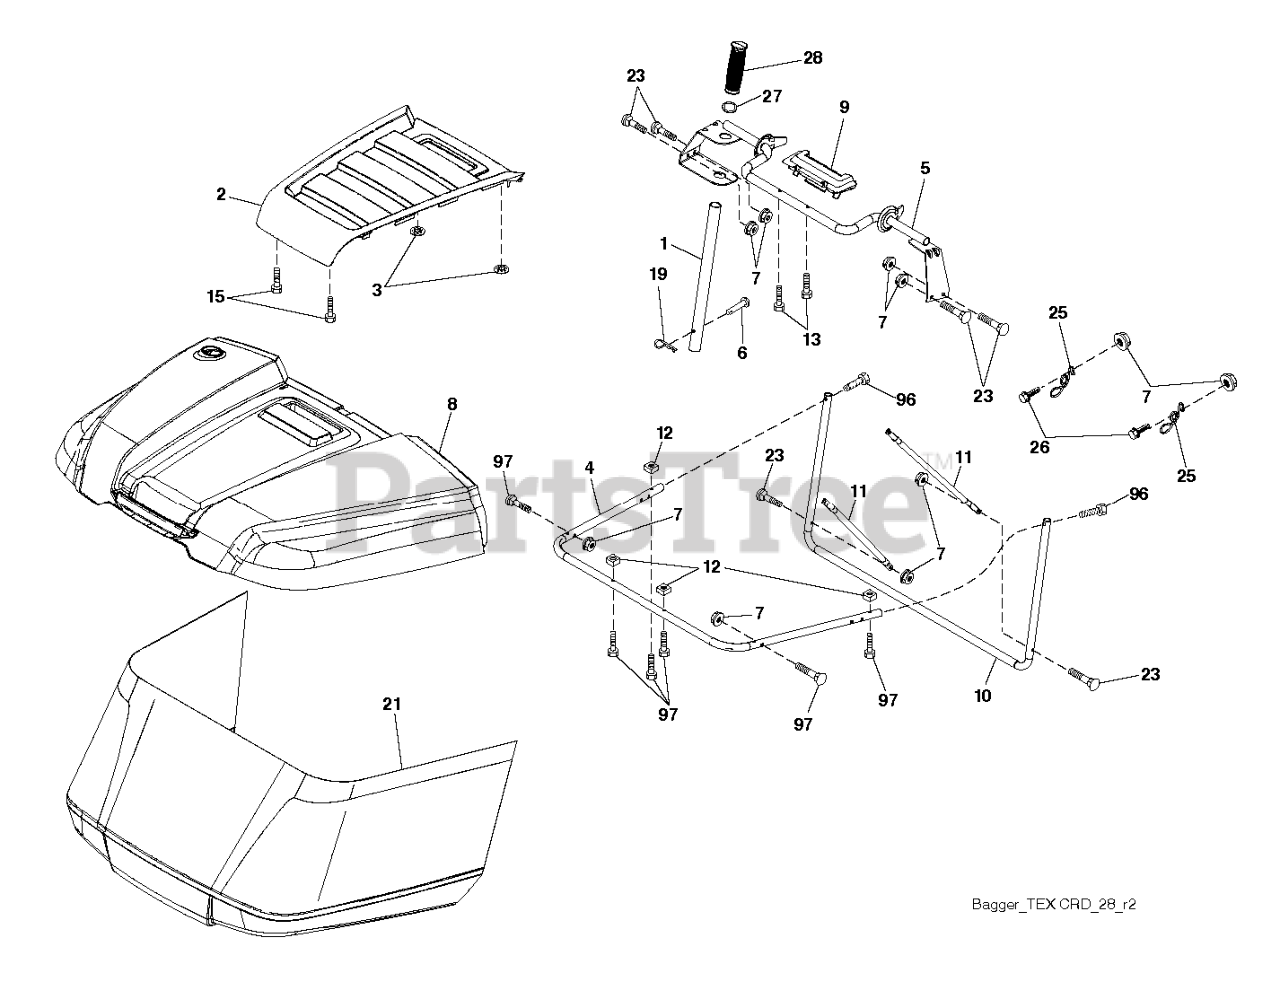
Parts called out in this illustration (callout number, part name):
1	TUBE.HANDLE.BAGGER.CRD/SRD.BLA
2	APPLIQUE.TOP.BAG.SRD.ORANGE
3	NUT.PUSH.156
4	SUBASM.TOP.BAGGER.TUBE
5	FRAME.ASM.TOP.BAGGER.SRD
6	RIVET,DRILLED
7	NUT T
8	BAGGER.TOP.SRD.APPLIQUE
9	INSERT.HANDLE.BAGGER.(2 2)
10	FRAME FRAME.FRONT.TEX.CRD
11	BRACE BRACE SIDE TUBE
12	NUT.SQUARE.1/4
13	SCREW.1/4X1.150.HXWSH
15	SCREW,#8.FLAT.HEAD.DRILL.TIP
19	PIN.COTTER.5/16.BOW TI
21	BAG SUBASM. TEX CRD GEN 2 HUSQ
25	SPRING.LATCH.BAGGER.SRD
26	SCREW HEX CRT
27	RB GROMMET.RUBBER.SRD
28	GRIP.HANDLE.BLACK
96	SCREW.HEXCAP.1/4X-20X1.500
97	SCREW.TORX.BUTN.HD.1/4-20-1.5"
